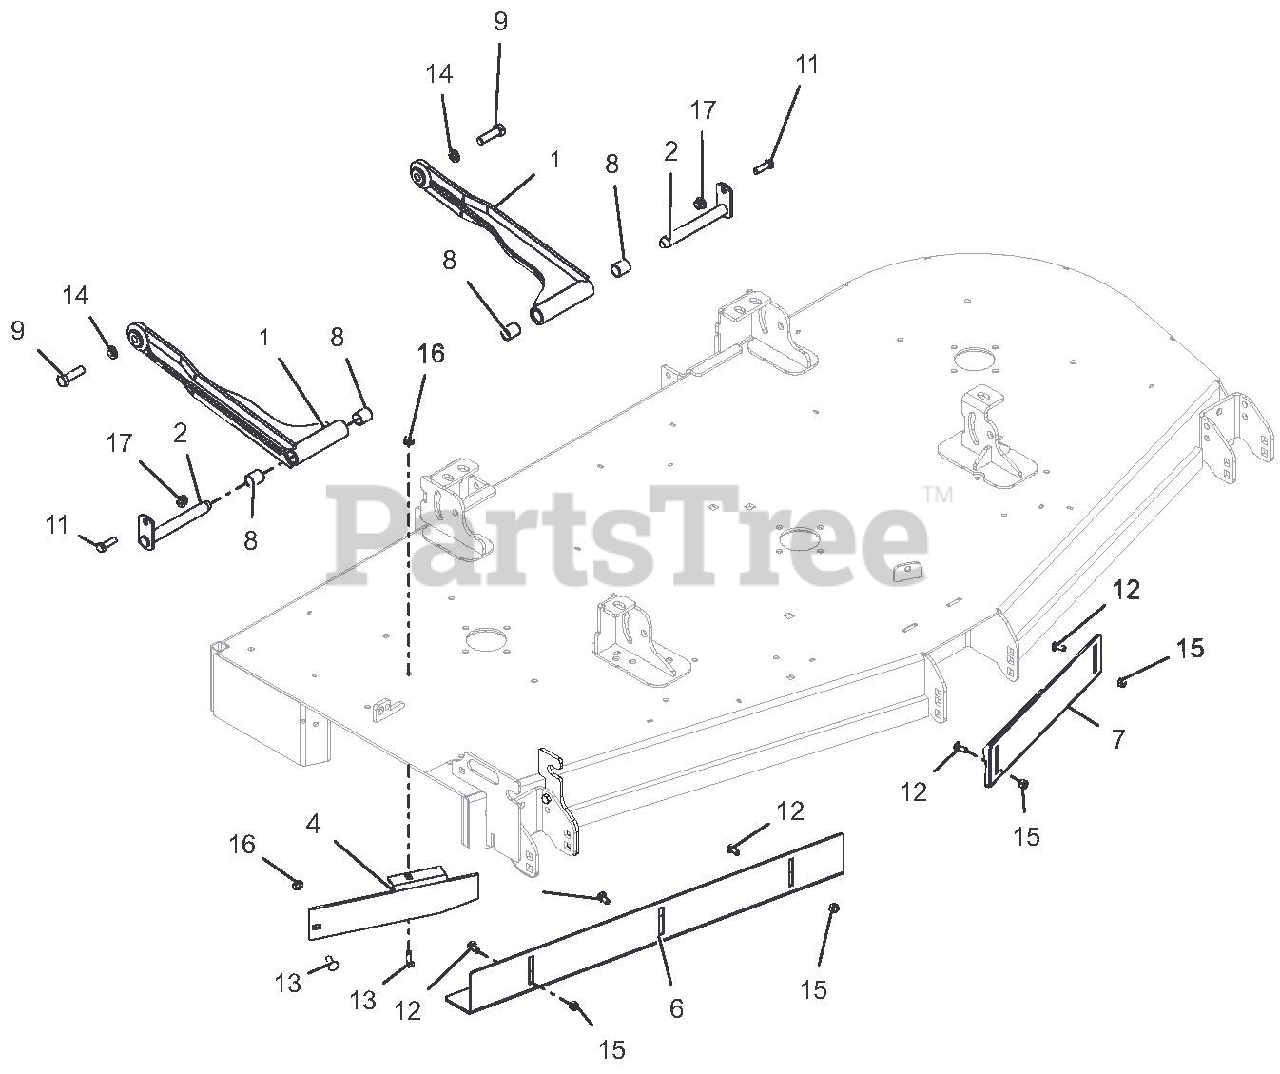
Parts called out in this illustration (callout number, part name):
1	WMT, DECK STABILIZER ARM
2	WLDMT, MOWER MTG. PIN
4	BAFFLE, 72" DISCHARG
6	BAFFLE, 72" RH VACCUM
7	BAFFLE, 72" LH VACCUM
8	BRG, .750 X .875 X 1.000
9	BLT-HEX .50-13 X 1.75 GR5 YWZC EP80
11	BLT-HEX .38-16 X 1.25 GR5 YWZC
12	BLT-RDHDSQNK .31-18 X .75 G5 YWZC
13	BLT-RDHDSQSHNK .31-18X1.00 G5 Y
14	WSHR-LK .50X.125 REG YWZC
15	NUT-LK-NYL .312-18 YWZC
16	NUT-LK-NYL-FLG .31-18 YWZC
17	NUT-LK-NYL-FLG .38-18 YWZC
